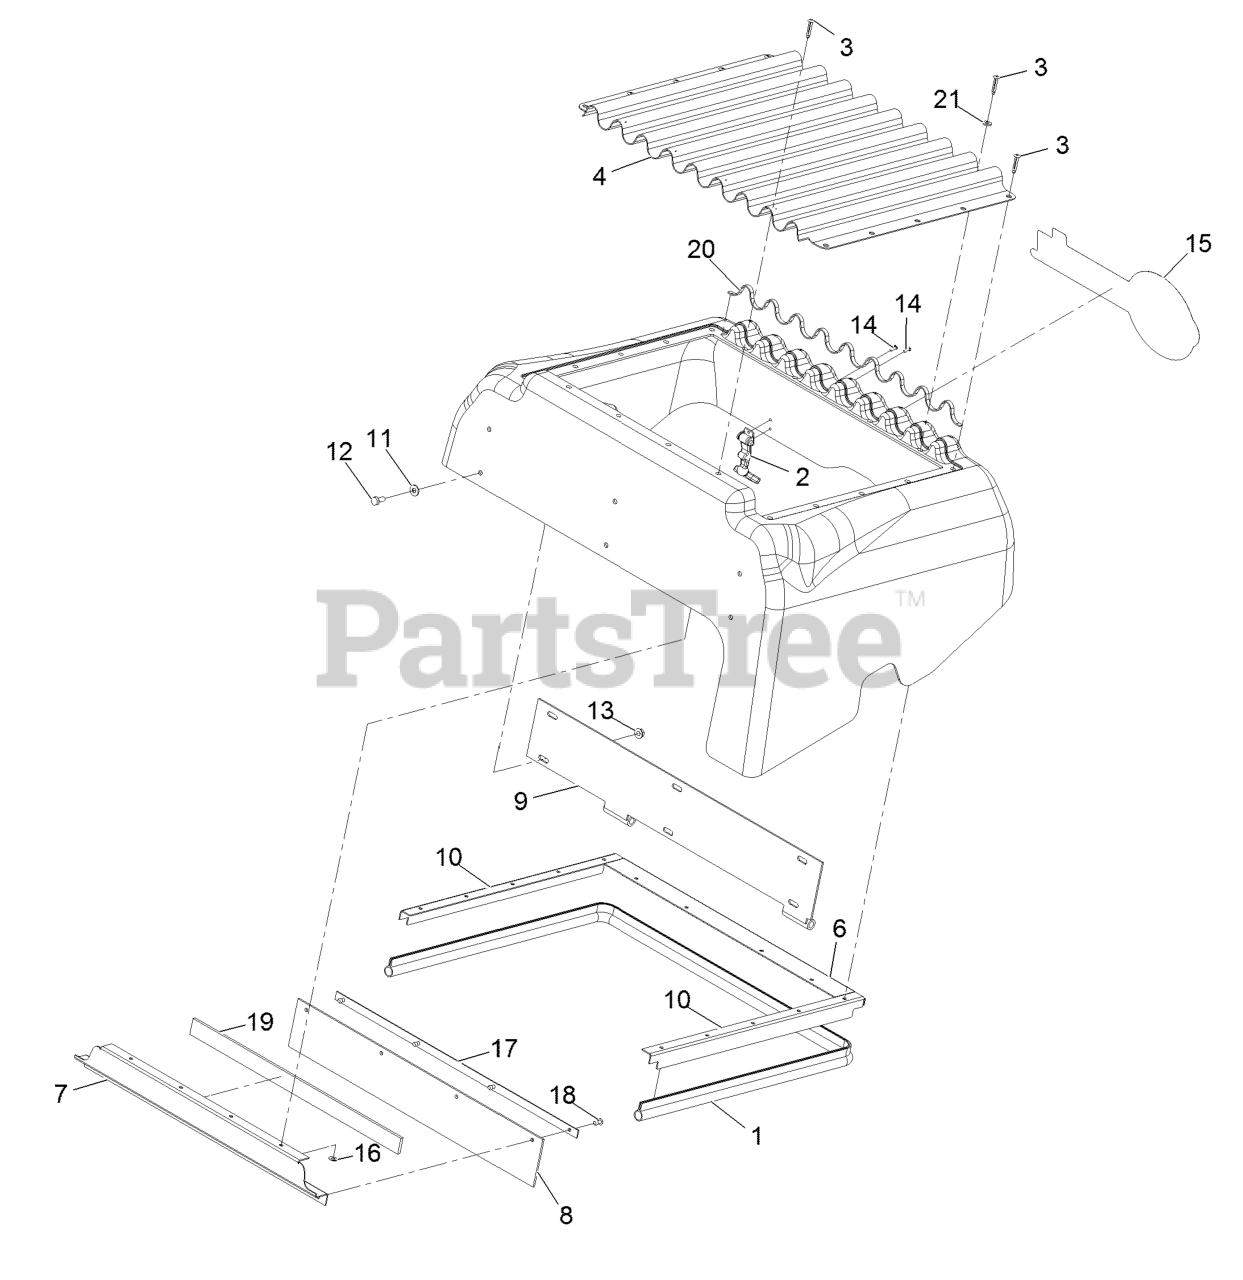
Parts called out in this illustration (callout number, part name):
1	Seal-Trim 54.6
2	LATCH-RUBBER
4	SCREEN, RADIATOR
6	MOUNT-SEAL REAR
7	MOUNT-SEAL FRONT
8	SEAL-RADIATOR HOOD
9	WLD, HINGE
10	MOUNT-SEAL SIDE
11	WASHER-FLAT
12	SCREW-HH
15	DECAL,EXMARK
16	WASHER-SPRING
17	PLATE-SEAL BACKUP
18	Rivet-Pop
19	SEAL-FRONT SCREEN
20	SEAL-REAR SCREEN
21	WASHER-FLAT
